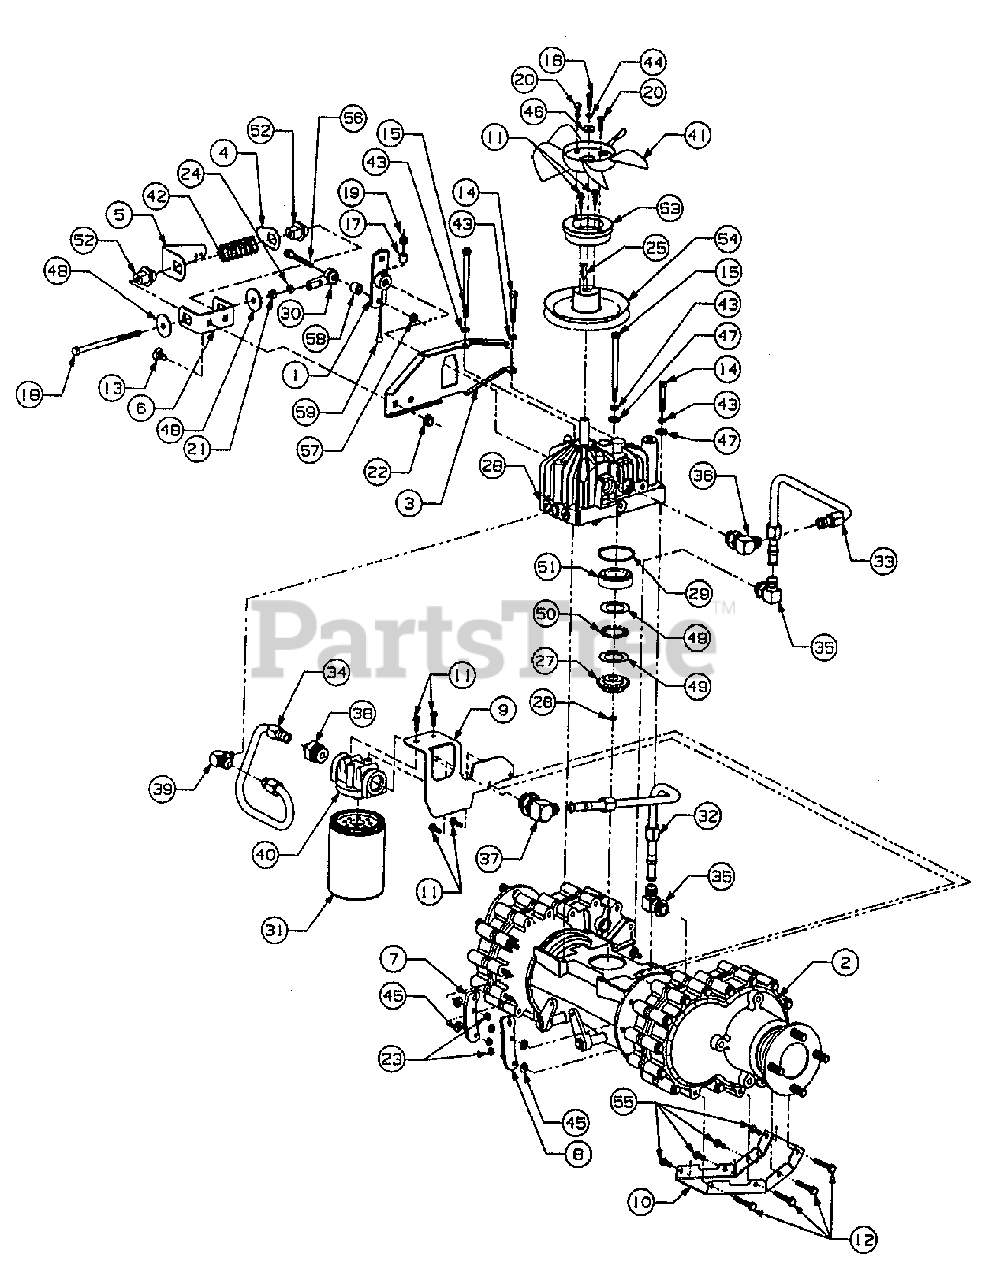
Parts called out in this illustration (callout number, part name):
1	Lever, Forward & Reverse
2	Transmissin Assembly, Complete
3	Plate, Neutral Mechanism Mtg
4	Stop, Switch
5	Mount, Switch
6	Bracket, Neutral Mechanism
7	Plate, Left Cable
8	Plate, Right Cable
9	Bracket, Oil Filter
10	Plate, Skid
11	Screw, Hex Wash Hd Tapp, 1/4-20 x .75
12	Screw, Hex Wash Hd Tapp, 1/4-20 x 2.31
13	Bolt, Sht Nk Carriage, 3/8-16 x .75 Gr 5
14	Screw, hex Cap, 5/16-18 x 2.0 Gr 5
15	Screw, Hex Cap, 5/16-18 x 4.75 Gr 5
16	Screw, Hex Cap, M6-1.0 x 20mm Gr 10.9
18	Screw, Hex Cap, 5/16-24 x 5.37 Gr 5
19	Nut, Nylon Lock, 10-24
20	Screw, Hex Cap w/Patch, 1/4-20 x .75 Gr 5
21	Nut, Hex Insert Lock, 5/16-24
22	Nut, Hex Flanged Lock, 3/8-16
23	Nut, Hex Top Lock, 1/4-20
24	Nut, Hex Jam, 5/16-24 gr 5
25	Key, Square, 5mm x 5mm x 25mm
26	Ring, Snap, .500 Dia Shaft
27	Gear, Input Pinion-20T
28	Pump, Hydrostatic
29	O-Ring, 2.237 ID x .103 Thk
30	Rod End, Spherical
31	Filter, Oil
32	Tube, Filter Inlet
33	Tube, Return
34	Tube, Hydro Inlet
35	Elbow, 90 Deg w/O-Ring
35	O-Ring, 1/2 OD Tube
36	Elbow, 90 Deg w/O-Ring
36	O-Ring, 3/4 OD Tube
37	Elbow, 90 Deg w/O-Ring
37	O-Ring, 3/4 OD Tube
38	Connector, Straight w/O-Ring
38	O-Ring, 3/4 OD Tube
39	Elbow, 90 Deg w/O-Ring
39	O-Ring, 1/4 Od Tube
40	Head, Filter
41	Fan, Hydro 8''
42	Spring, Compression, 1.20 OD x 2.70
43	Washer, Lock, 5/16
44	Washer, Lock, 1/4
45	Washer, Flat, .25 x .62 x .0515 Thk
46	Washer, Flat, .25 x .750 x .119 Thk
47	Washer, Flat, .312 x .750 x .119 Thk
48	Washer, Flat, .206 x .448 x .105 Thk
49	Washer, Thrust, 1.25 x 1.937 x .031 Thk
50	Bearing, Thrust, 1.25 x 1.937 x .0781 Thk
51	Spacer, Input Pinion
52	Guide, Neutral Stop
54	Pulley, Transmission Drive
55	Screw, Hex Wash Hd Tapp, 1/4-20 x .50
56	Screw, Hex Cap, 5/16-18 x 1.38 Gr 5
57	Nut, Hex Flange Lock, 5/16-18 Gr 5
58	Spacer, .317ID x .625OD x .343
59	Screw, Socket Hd, 10-24 x 1.5
